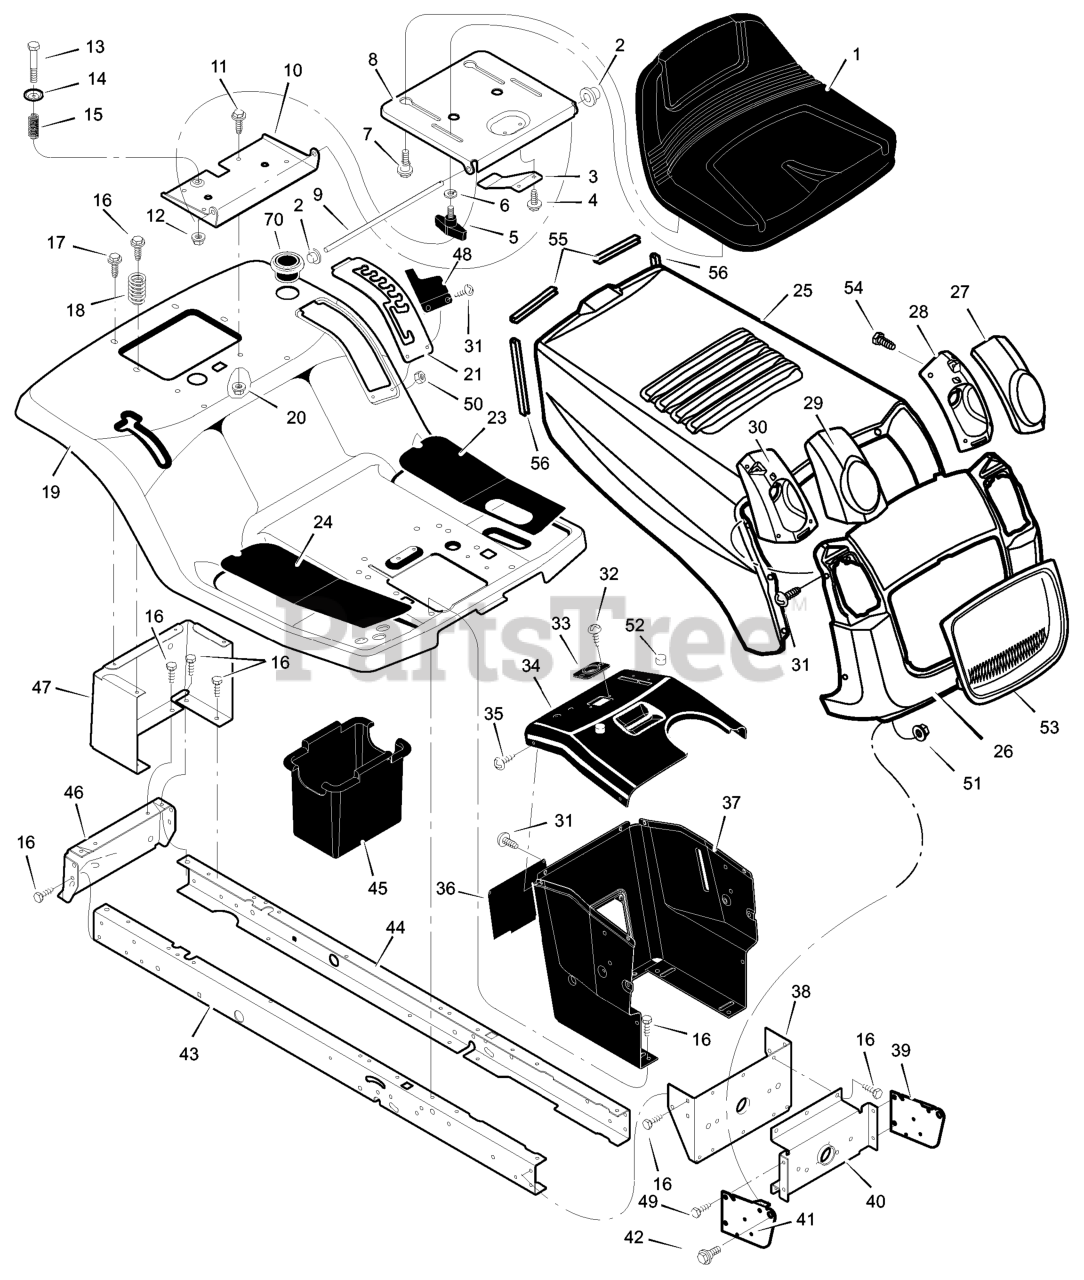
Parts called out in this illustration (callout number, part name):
1	Seat
2	Cap, Push On
5	Bolt, Wing
6	Washer
7	Bolt, Shoulder
8	Support, Seat
9	Rod, Pivot
10	Bracket, Pivot
11	Bolt
13	Bolt, Shoulder
15	Spring
19	Deck, Seat
20	Nut
21	Plate, Index
23	Mat, Left
24	Mat, Right
27	Lens, Left
28	Housing, Left Headlamp
29	Lens, Right
30	Housing, Right Headlamp
31	Screw
33	Bearing, Steering
36	Panel, Access
37	Support, Dash
38	Bracket, Rear Hanger
39	Support, Left Grille
40	Axle, Hanger
41	Support, Right Grille
42	Bolt, Shoulder
43	Frame, Right
44	Frame, Left
45	Container, Battery
46	Plate, Hitch
47	Panel, Rear
48	Cover, Detent
52	Bumper
53	Insert, Grille
55	Trim, Hood (3.75")
56	Trim, Hood (6.5")
70	Holder, Cup
